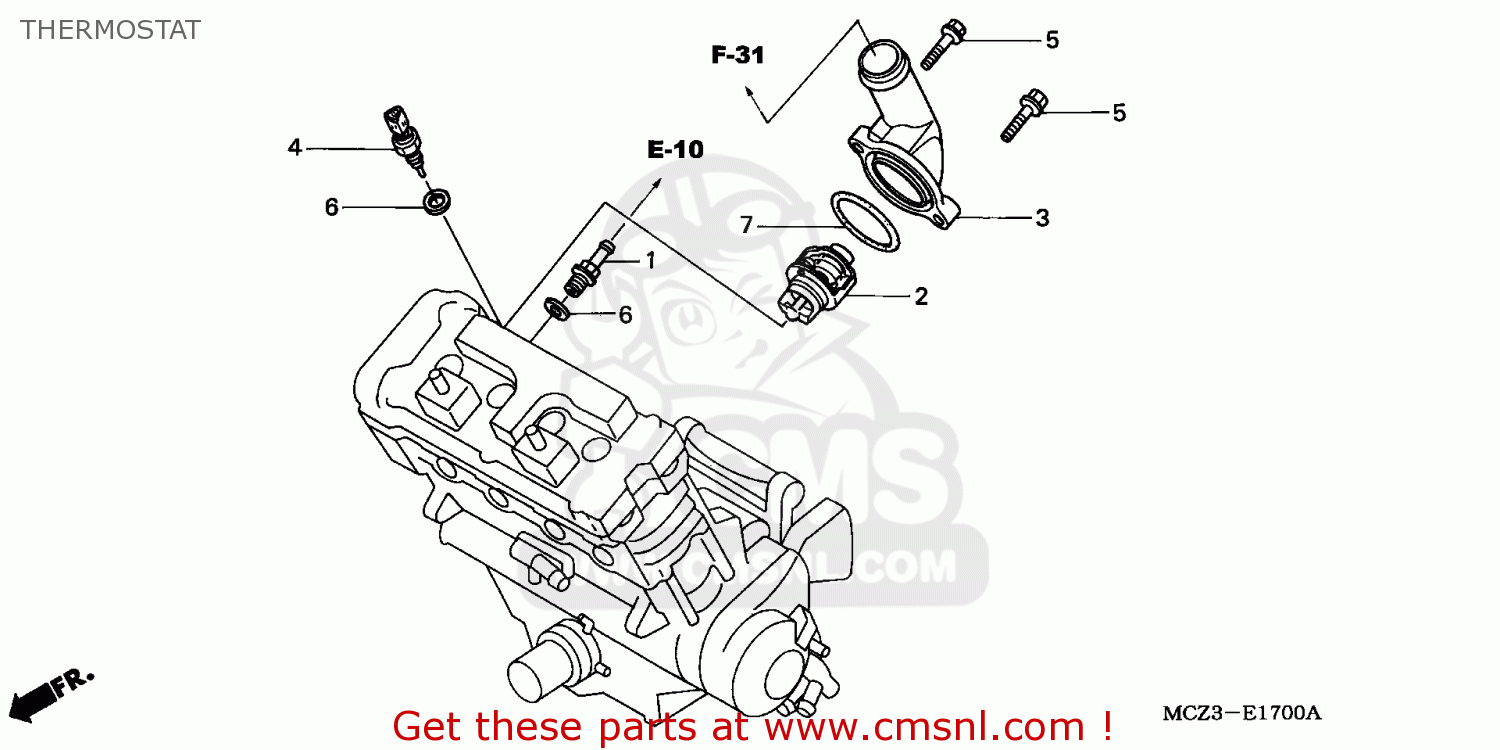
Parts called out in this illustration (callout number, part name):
1	JOINT,HOSE
2	THERMOSTAT
3	COVER,THERMOSTAT
4	SENSOR ASSY TW
5	BOLT,FLANGE 6X22
6	WASH,SPECIAL,12MM
7	O-RING,47.5X2
